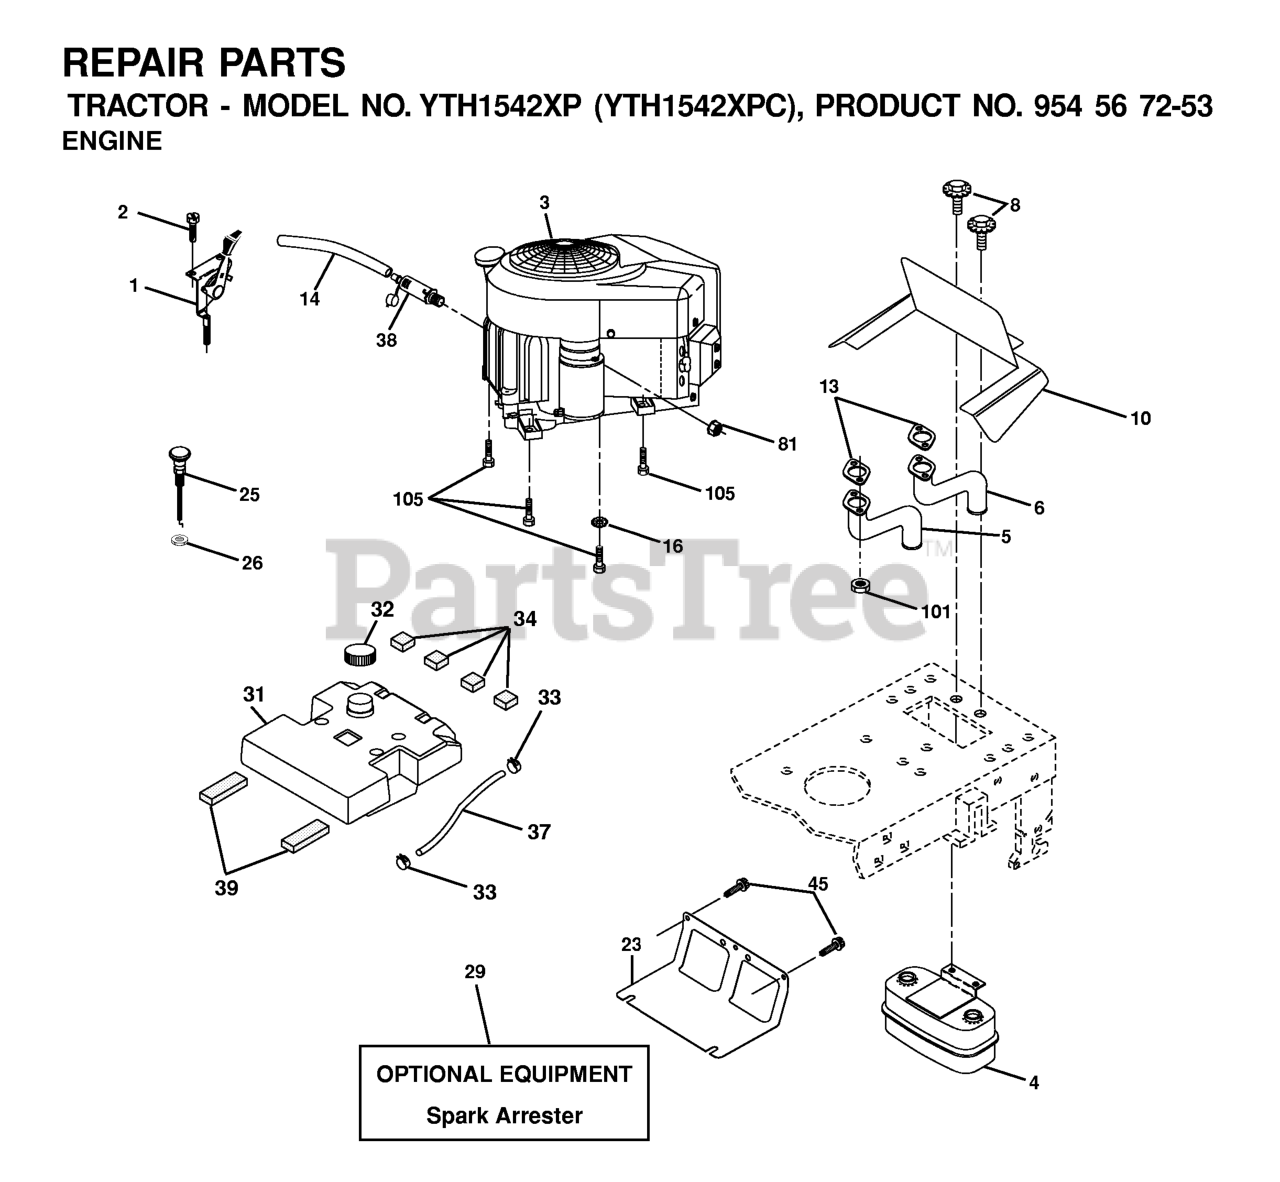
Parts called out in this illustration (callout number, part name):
1	CONTROL, THROTTLE
2	SCREW
4	MUFFLER.TWIN.CYL.LOW.TONE
5	EXHAUST.TUBE.LH.KAWASAKI.
6	EXHAUST.TUBE.RH.KAWASAKI.
8	BOLT.5/16-18UNCX3/4 W/SEMS.BLK
10	RP SHIELD HEAT MUFFLER
14	TUBE, DRAIN OIL ASM.
16	LOCKWASHER
23	SHIELD.BROWNING.DBR.GUARD
25	CHOKE CONTROL
26	Nut Keps 3/8 - 24 UNF
29	KIT.SPARK ARRESTOR 794945 B&S
31	TANK.FUEL(3.5.GAL)
32	FUEL CAP/GAUGE
33	HOSE CLAMP
34	PAD-SPACER LT
37	REPL BY 532 00 85-43
39	PAD IDLER TI
45	SCREW, 3/8-16X3/4
81	NUT
101	FLANGE NUT
105	SCREW 3/8-16X1
